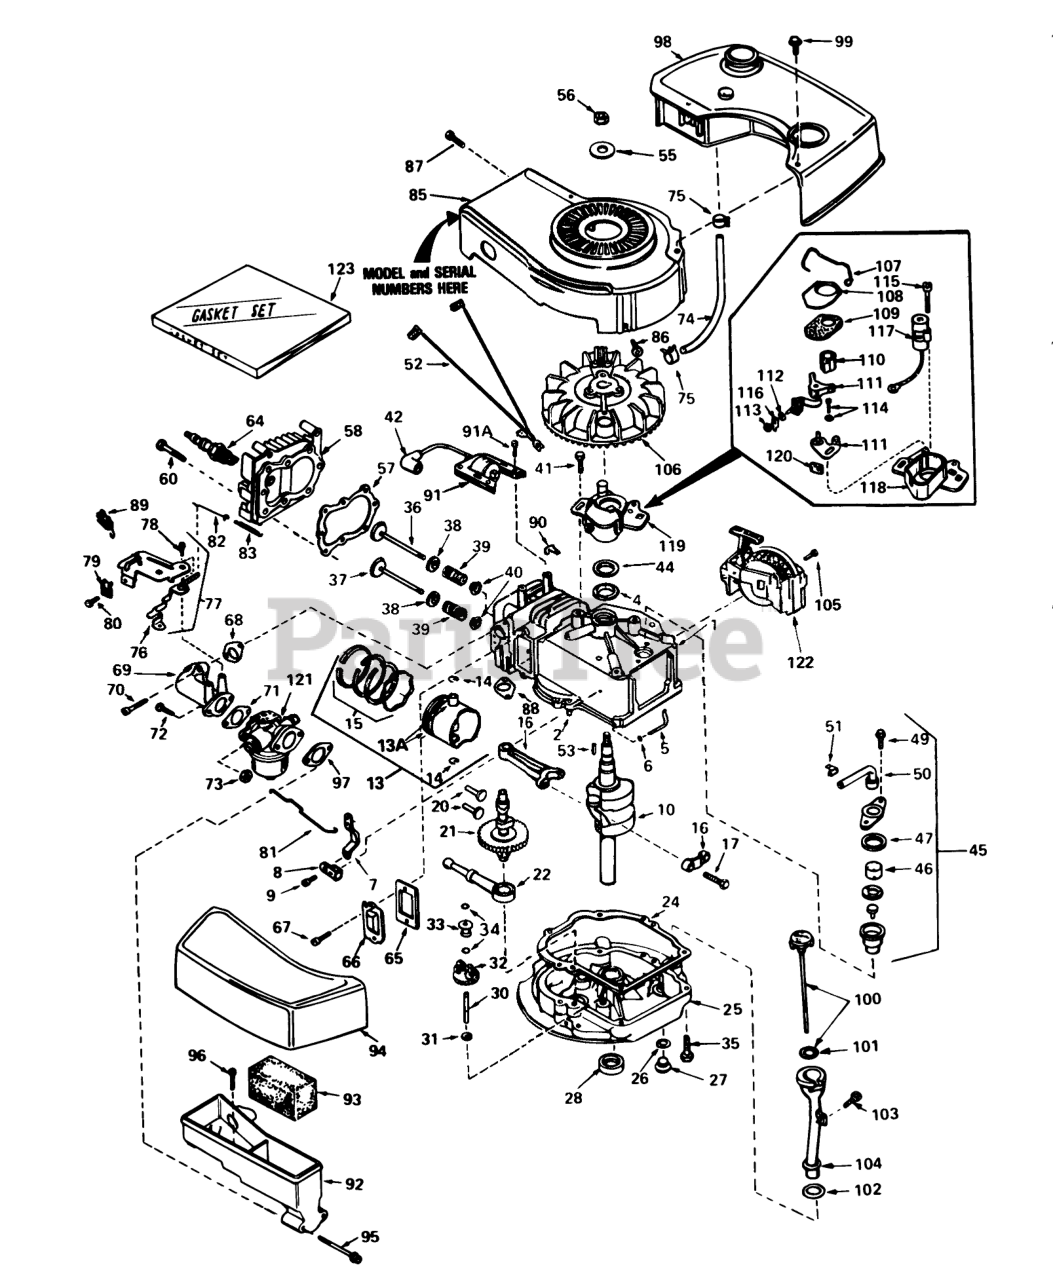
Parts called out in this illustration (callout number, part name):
1	Cylinder Assy. (Incl. Ref. #2 & 4)
2	Pin-Dowel
4	Seal-Oil
5	Rod, Governor (Incl. Ref. #6)
6	Washer-Flat
7	Governor Lever
8	Clamp-Lever, Governor
9	Screw
10	Crankshaft
13	Piston, Pin & Ring Assy. (Std.) (Incl. Ref. #13A, 14 & 15)
13	Piston, Pin & Ring Assy. (.010 oversize) (Incl. Ref. #13A, 14 & 15)
13	Piston, Pin & Ring Assy. (.020 oversize) (Incl. Ref. #13A, 14 & 15)
13A	Piston & Pin Assy. (Std.) (Incl. Ref. #14)
13A	Piston & Pin Assy. (.010 oversize) (Incl. Ref. #14)
13A	Piston & Pin Assy. (.020 oversize) (Incl. Ref. #14)
14	Ring-Retaining, Piston Pin
15	Ring Set (Std.)
15	Ring Set (.020" OS)
15	Ring Set (.010" OS)
16	Rod Assy ., Connecting (Incl. Ref. #17)
17	Bolt-Rod, Connecting
20	Lifter-Valve
21	Camshaft(Mech.Comp. Release)
22	Oil Pump ASM
24	Gasket, Mounting
25	Flange Assy., Mounting (Incl. Ref. #26 thru 30)
26	Gasket-Oil Drain
27	Plug Oil Drain
28	Seal Oil
30	Shaft-Governor
31	Washer-Flat
32	Gear Assy., Governor (Incl. Ref. #31)
33	Spool-Governor
34	Ring-Retaining
35	Screw (1/4-20 x 1-1/4)
36	Valve, Intake (Std.) (Incl. Ref. #40)
36	Valve, Intake (1/32" oversize) (Incl. Ref. #40)
37	Valve, Exhaust (Std.) (Incl.Ref. #40)
37	Valve, Exhaust (1/32" oversize) (Incl. Ref. #40)
38	Cap-Upper Valve Spring
39	Spring-Valve
40	Cap-Valve, Spring
42	Cover-Spark Plug
44	Gasket Stator
45	Breather Assy. (Incl. Ref. #46 thru 51)
46	Element-Breather
47	Gasket-Breather
49	Screw (10-24 x 9/16)
50	Tube, Breaker
51	Clip, Breather
52	Wire Ground
53	682488 LB GRASS HI-
55	Washer-Belleville
56	Nut-Flywheel
57	63573 GIL 42 SNWTHW
58	Head-Cylinder
60	Screw
64	Plug, Spark (J17LM or equiv.)
64	Plug, Spark (Champion RCJ-8)
65	Gasket-Breather
66	Cover-Valve
68	Gasket-Intake
69	Pipe, Intake (Incl. Ref. #68)
70	Screw (1/4-20 x 1)
71	Gasket-Carburetor
72	Screw (1/4-28 x 7/8)
73	Nut and Lock Washer (1/4-28)
74	Line-Fuel
75	Clamp-Line, Fuel
76	Lever Control
77	Control Assy., Speed (Incl. Ref. #76, 78 & 80)
78	Screw, Hex Washer Hd Shoulder Self-Tap
79	Conduit
80	Screw (10-32 x 3/8)
81	Link-Throttle
82	Link Governor Spring
83	Spring Governor
85	Housing, Blower
86	Screw
87	Screw (10-24 x 9/16)
88	Gasket Exhaust
89	Terminal
90	Clip-Wire
91	Lamination & Coil Assy. (Incl. Ref. #42)
91A	Screw
92	Body Air Cleaner
93	Filer, Air
94	Cove, Air Cleaner
95	Screw Fil Hd.
96	Screw, Hex Hd.
97	Gasket-Air Cleaner
98	Tank, Fuel
99	Screw (10-32 x 35/64)
100	Dipstick, Oil (Incl. Ref. #101) (Twist Lock)
103	Screw (10-32 x 1/2)
104	Tube-Oil Fill
105	Screw (1/2-20x5/8)
106	FIywheel
107	Spring Breaker Box
108	Cover-Dust
109	Gasket-Dust Cover
110	Cam-Breaker
111	Breaker Assy.
114	Breaker Screw
115	Condenser Screw
116	Terminal, Ground
117	Condenser
118	Stator Plate
119	Stator Assy. (Incl. Ref. #107, 111 thru 118 & 120)
120	Felt,Cam Wiper
121	Carburetor (Incl. Ref. #71)
122	Starter-Sidemount
123	Gasket Set (Incl. Items Marked)
